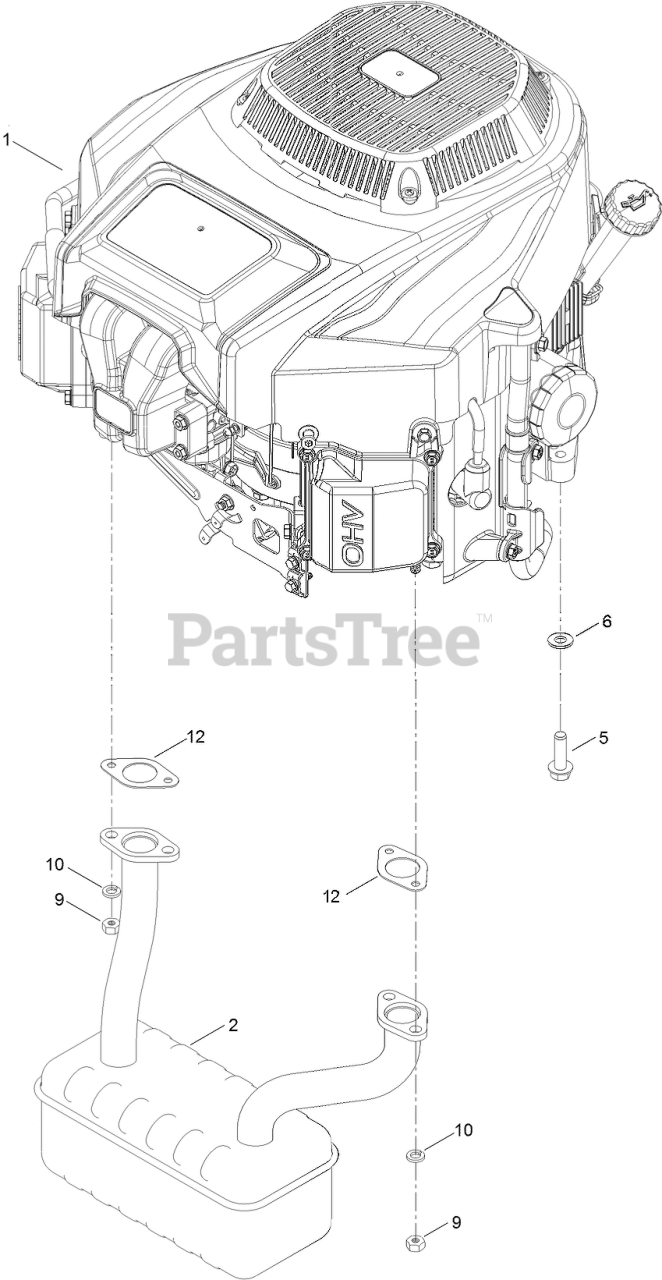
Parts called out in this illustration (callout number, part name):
1	ENGINE-2P77F
2	MUFFLER
5	SCREW-THD
6	WASHER-FLAT
9	NUT-HH
10	WASHER-LOCK, SPLIT
12	GASKET-EXHAUST
